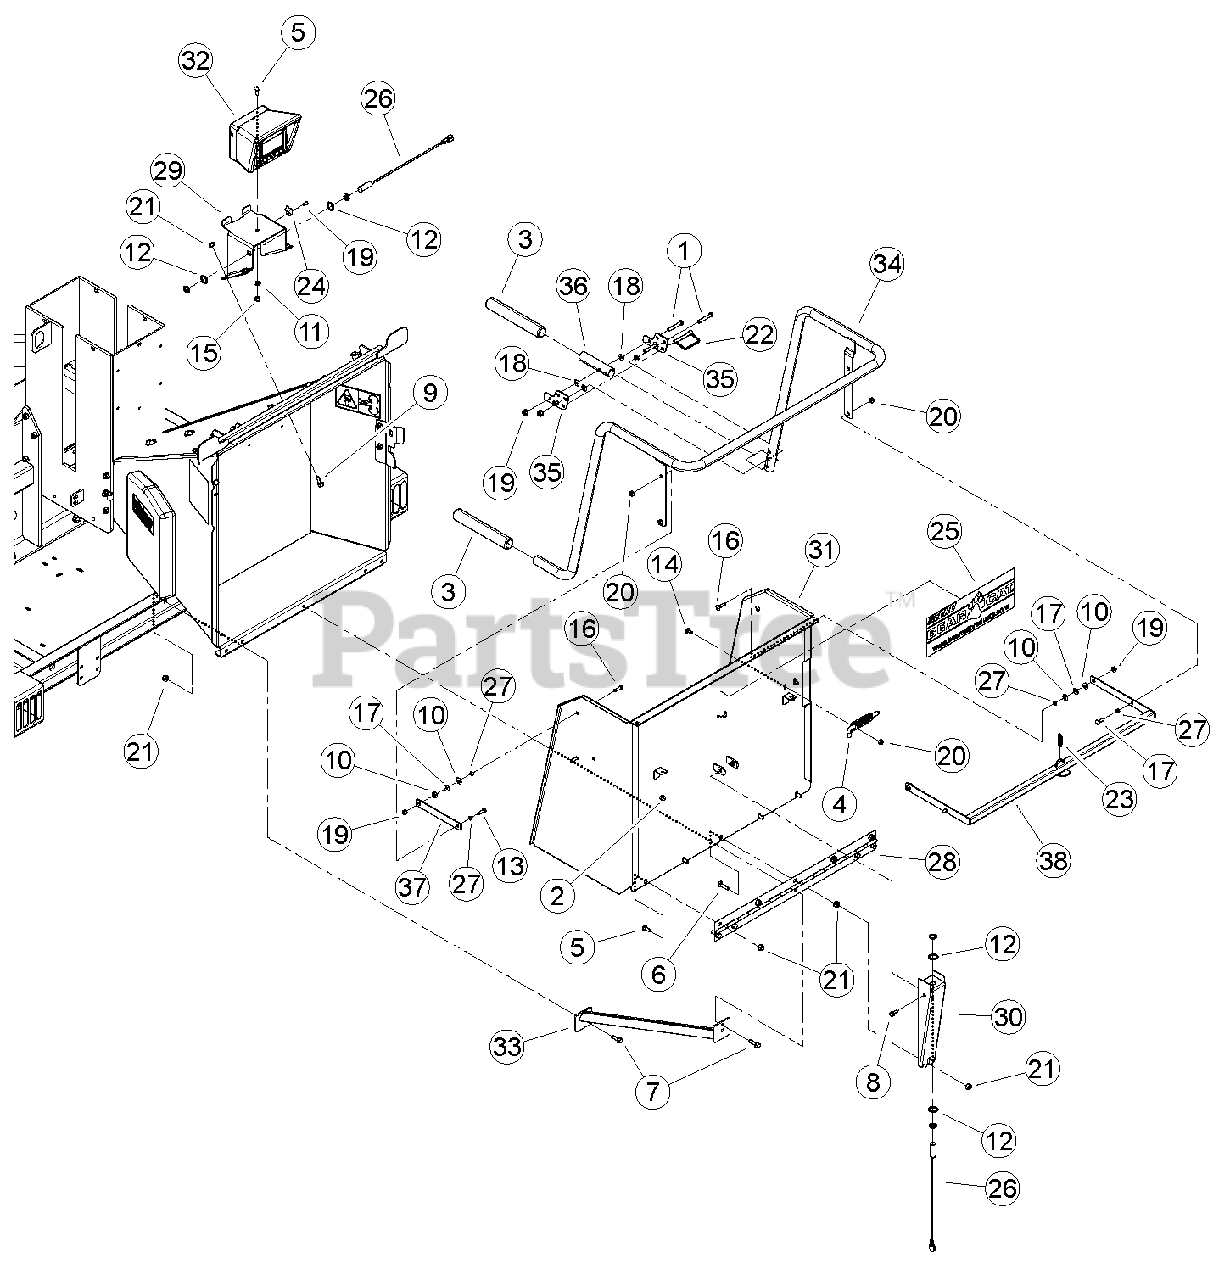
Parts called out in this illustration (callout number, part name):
1	BOLT, 3/8 X 2-1/4 HEX GR5 ZP
2	BUMPER, RUBBER
3	GRIP, 1.219 X 10.00
4	LATCH, RH HINGE
5	BOLT, 3/8 X 1" GR5 CRG NC ZP
6	BOLT, 3/8 X 1-1/2" GR5 CRG NC ZP
7	BOLT, 3/8 X 1-1/4 FLANGE NC
8	BOLT, 5/16 X 3/4 FLANGE NC
9	BOLT, 3/8 X 1 FLANGE NC
10	WASHER, 5/16" FLAT ZP
11	WASHER, 3/8" SAE FLAT ZP
12	WASHER, 3/4 INTERNAL LOCK
13	BOLT, 5/16 X 1" GR5 CRG ZP
14	BOLT, 5/16 X 3/4 GR5 CRG NC ZP
15	NUT, 3/8" NE NYLOCK ZP
16	BOLT, 5/16 X 1-1/4" GR5 CRG ZP
17	WASHER, 5/16" ID 7/8" OD NYLON FLAT
18	WASHER, 3/8" .062 TH NYLON FLAT
19	RIVET, AL BLIND 1/4 X 3/4 DOME HEAD
20	NUT, 5/16-18 NYLOCK-FLANGE
21	NUT, 3/8-16 NYLOCK FLANGE
22	PIN, 3/8" X 2-3/4" SNAP
23	SPRING, 1/2 X 2.00 LG ZP
24	CLAMP, CABLE MOUNT
25	DECAL, BEARCAT WEB
26	SENSOR, M18 PROXIMITY (REPLACEMENT PART)
27	SPACER, IDLER PIVOT
28	HINGE, EXTENSION TRAY
29	MOUNT, 5/8/9" DDC
30	MOUNT, 5/8/9" KNEEBAR PROX SENSOR
31	WELDMENT, INFEED TRAY
32	ASSEMBLY, DDC ENCLOSURE
33	WELDMENT, CHUTE SUPPORT
34	WELDMENT, 9" TOWABLE KNEE BAR
35	PLATE, 9" TOWABLE KNEE BAR
36	TUBE, 9" TOWABLE KNEE BAR HANDLE
37	LINK, PARALLEL
38	WELDMENT, KNEEBAR PIVOT
